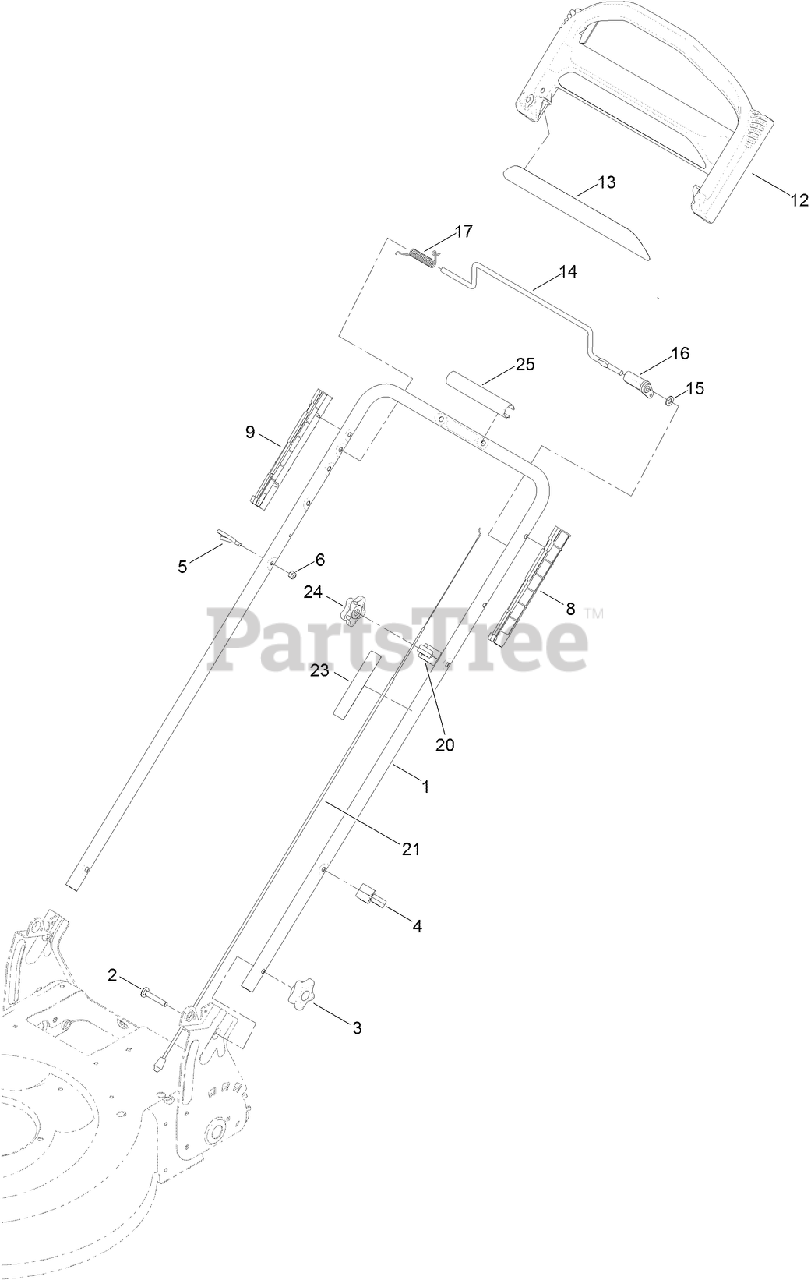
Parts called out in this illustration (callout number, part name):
2	Screw-CARR
3	KNOB-HANDLE
4	GUIDE-CABLE
5	GUIDE-ROPE
6	NUT-LOCK, NI
8	GUIDE-LH
9	GUIDE-RH
12	HANDLE-CONTROL
14	BAR-CONTROL, TRACTION
15	WASHER-PLAIN
16	LEVER-TRACTION
17	Spring-Torsion
20	ANCHOR-CABLE
21	CABLE-TRACTION
23	DECAL-TRACTION, ADJUST
24	KNOB-HANDLE, LOCKING
25	COVER-HANDLE
